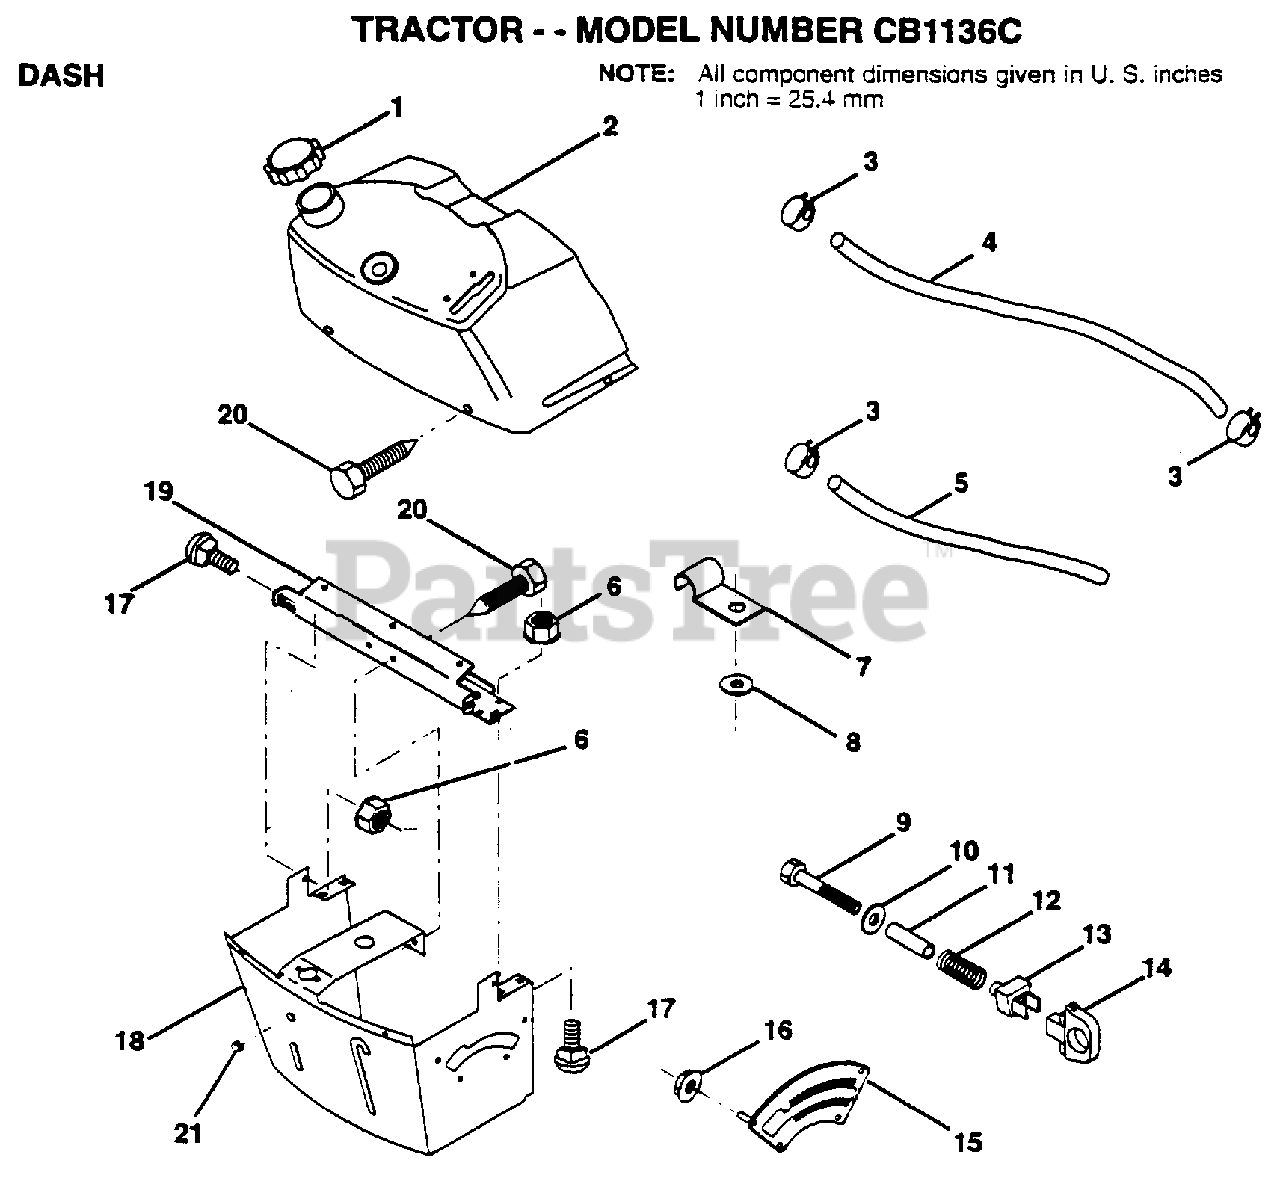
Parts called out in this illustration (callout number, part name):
1	CAP BLK FUEL LR
2	TANK.ASM.DASH.LR
3	HOSE CLAMP
5	FUEL LINE T
6	NUT HXKEP 1/4X20
7	CLIP T
8	WASHER PM
9	BOLT
11	SPACER SPLIT
12	SPRING M
13	"KNOB,HGT RETAINER"
14	KNOB
15	ADJUSTER QUAD
16	NUT
17	BOLT
18	SUPT ASSY DASH
19	CROSS BRACE
20	SCREW.1/4-20X1/2
21	PLUG DOME
